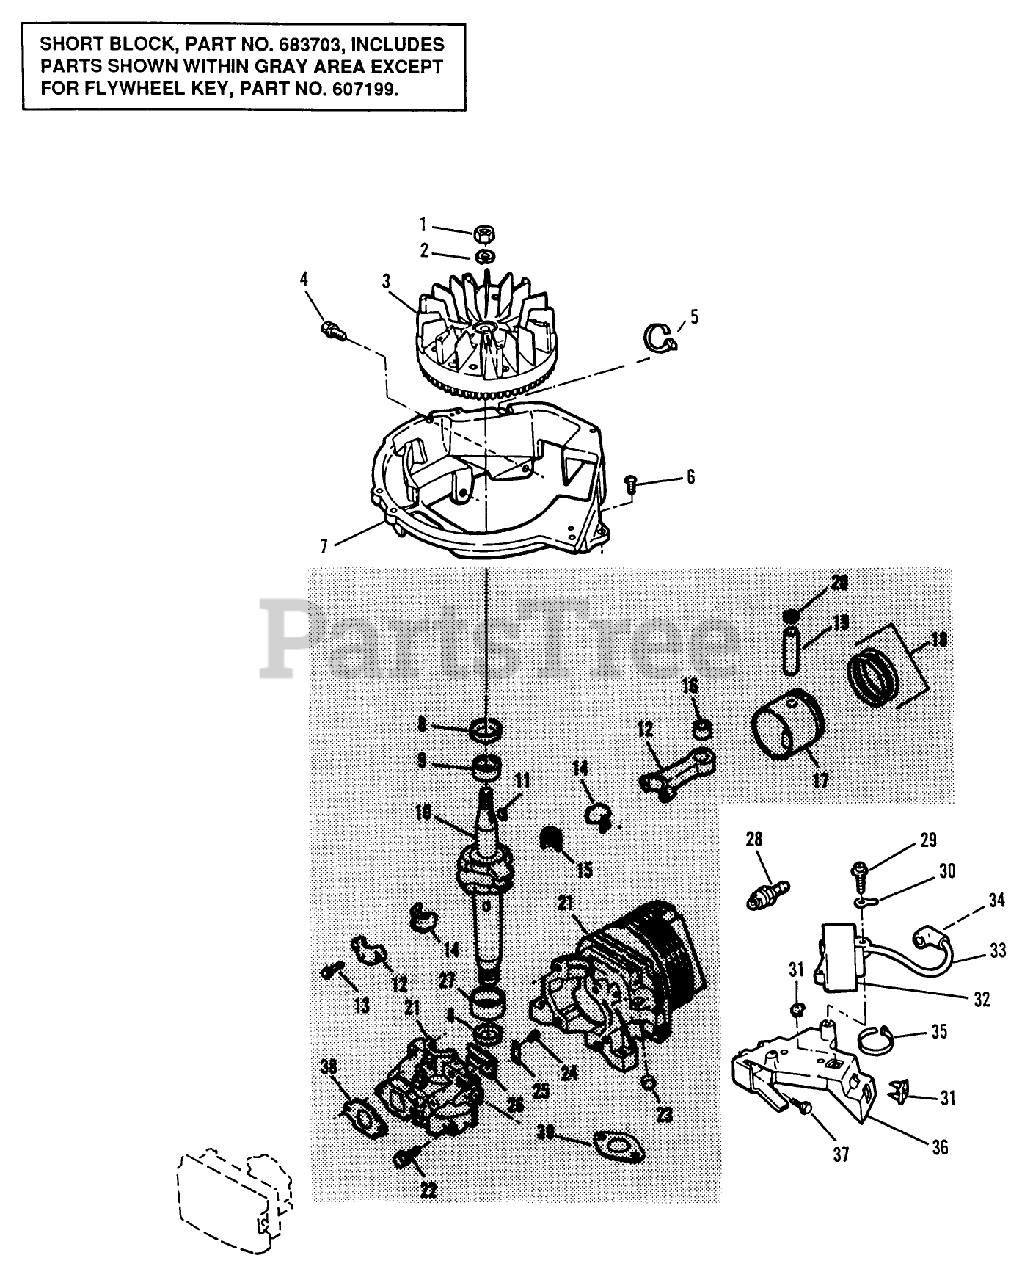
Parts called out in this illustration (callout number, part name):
1	NUT
4	SCREW-SEMS
6	SCREW F
8	SEAL-OIL
9	BEARING V
11	KEY
13	SCREW-HSH
14	LINER ASM
15	BEARING-NEEDLE
16	BEARING AY F
20	RING-RETAINING
22	SCREW-H.W.HD. F
23	PLUG-CORE VF
24	SCREW-HH
25	PLATE-BACKUP, REED
27	BEARING V
30	TERMINAL S
31	NUT-CLIP
33	HT LEAD&COVER XEV
36	C.D. BRKT F
38	GASKET CARB S
